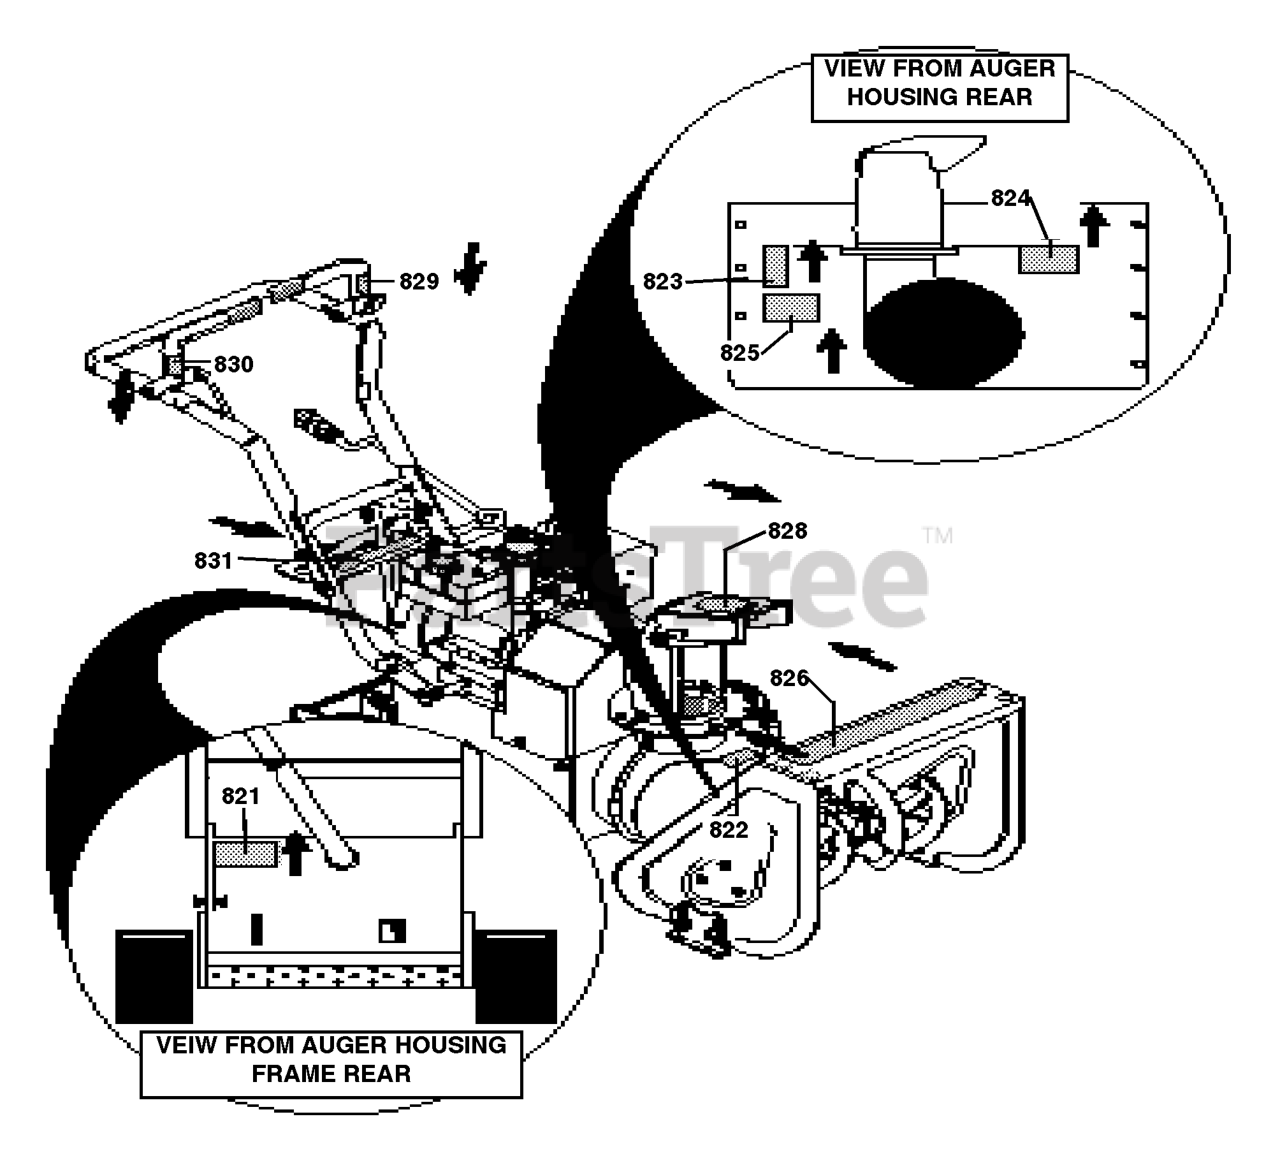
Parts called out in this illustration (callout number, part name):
821	NOT A SERVICABLE PART
822	DECAL-9" IMPELLAR
823	DECAL, DANGER CHUTE
824	DECAL-DANGER AUGER/FOOT
825	DECAL, DANGER
826	DECAL, ST624E
828	DECAL, CROWN
829	DECAL, TRACTION DRIVE ENG.
830	DECAL, AUGER DRIVE ENGAGE
831	DECAL, GEAR SELECTOR
